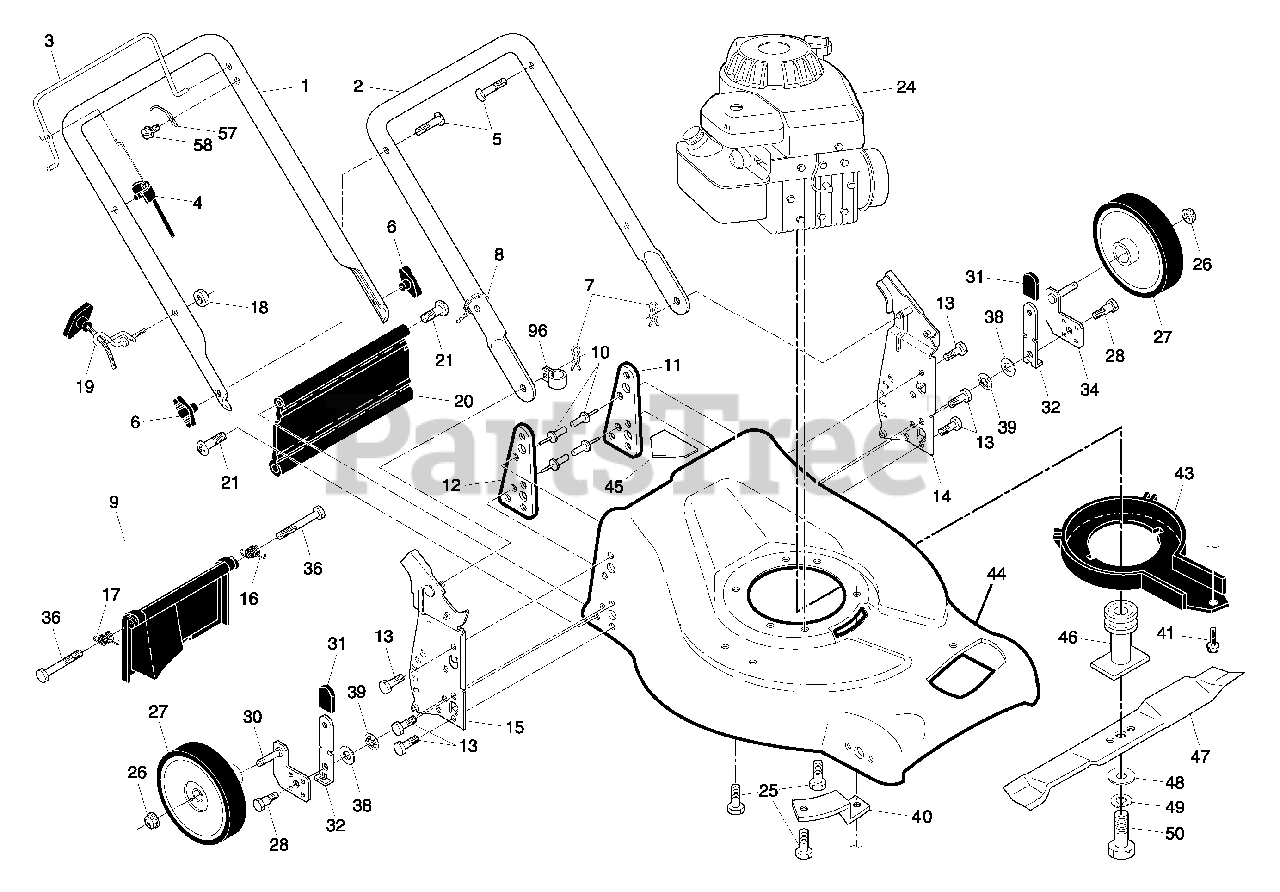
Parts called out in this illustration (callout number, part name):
1	Upper Handle
2	Lower Handle
3	Control Bar
4	Engine Zone Control Cable
5	Handle Bolt
6	Handle Knob
7	Hairpin Cotter
8	Wire Tie
9	Kit, Rear Door
10	Pop Rivet
11	Support Bracket, LH
12	Support Bracket, RH
13	Screw, Tapping 1/4-20 x 5/8
14	Handle Bracket Assembly, LH
15	Handle Bracket Assembly, RH
16	Spring, Rear Door, LH
17	Spring, Rear Door, RH
18	Nut, Hex 1/4-20
19	Rope Guide
20	Rear Skirt
21	Hinge Screw 1/4-20 x 1-1/4
25	Hex Head Thread Rolling Screw 3/8-16 x 1-1/8
26	Hex Flange Nut
27	Wheel & Tire Assembly
28	Shoulder Bolt 5/16-18 x 1-21/64
30	Axle Arm Assembly, Rear, RH
31	Selector Knob
32	Selector Spring
34	Axle Arm Assembly, Rear, LH
36	Bolt, Rear Door
38	Washer, Step 11/32 x 1-3/8 x 7/32
39	Push Nut
40	Mounting Bracket, Debris Shield
41	Screw, Debris Shield
43	Debris Shield
44	Kit, Lawn Mower Housing
45	Danger Decal
46	Blade Adapter / Pulley
47	Blade, 21"
48	Hardened Washer
49	Helical Washer
50	Hex Head Machine Screw, Grade 8, 3/8-24 x 1-3/8
57	Upstop Bracket
58	Screw
96	Clip, Cable
